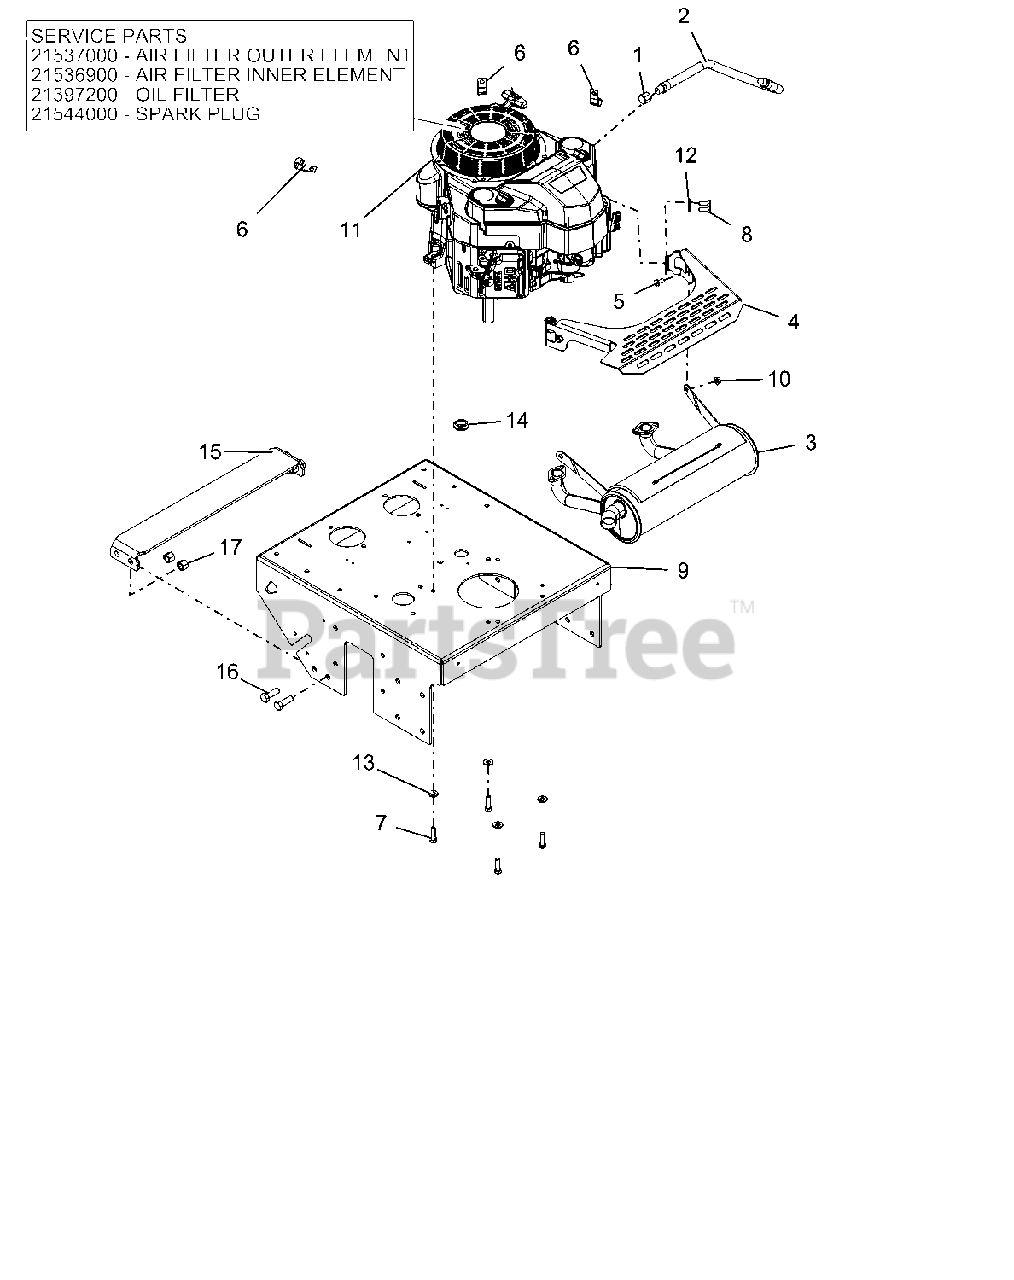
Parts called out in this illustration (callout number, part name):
1	PIPE, CAP 3/8 NPT FEMALE
2	DRAIN, M20 OIL
3	EXHAUST, KAWASAKI FS
4	SHIELD, MUFFLER-BLACK
5	SCR - HEX -FL M8X1.25X16 10.9
6	P-CLIP, .500 INSULATED
7	BLT-HEX .38-16X1.25 GR5 YWZC NYTORQ
8	@BLT-HEX M8-1.25X20 YWZC
9	ASSM, 48-52" FRAME W/DECALS
10	LOCKNUT, M8 X 1.25, FLANGED ZN
11	ENGINE, KAWASAKI FS600
12	WSHR-LK .31X.078 REG YWZC
13	WSHR, 3/8" SPRING DISC
14	GROMMET:RUB:.88IDx1.38ODX.14GR
15	PLATE, ENGINE BED REAR 52/48-RED
16	BLT-HEX .50-13X1.50 GR5 YWZC
17	NUT-LK-NYL .50-13 YWZC
